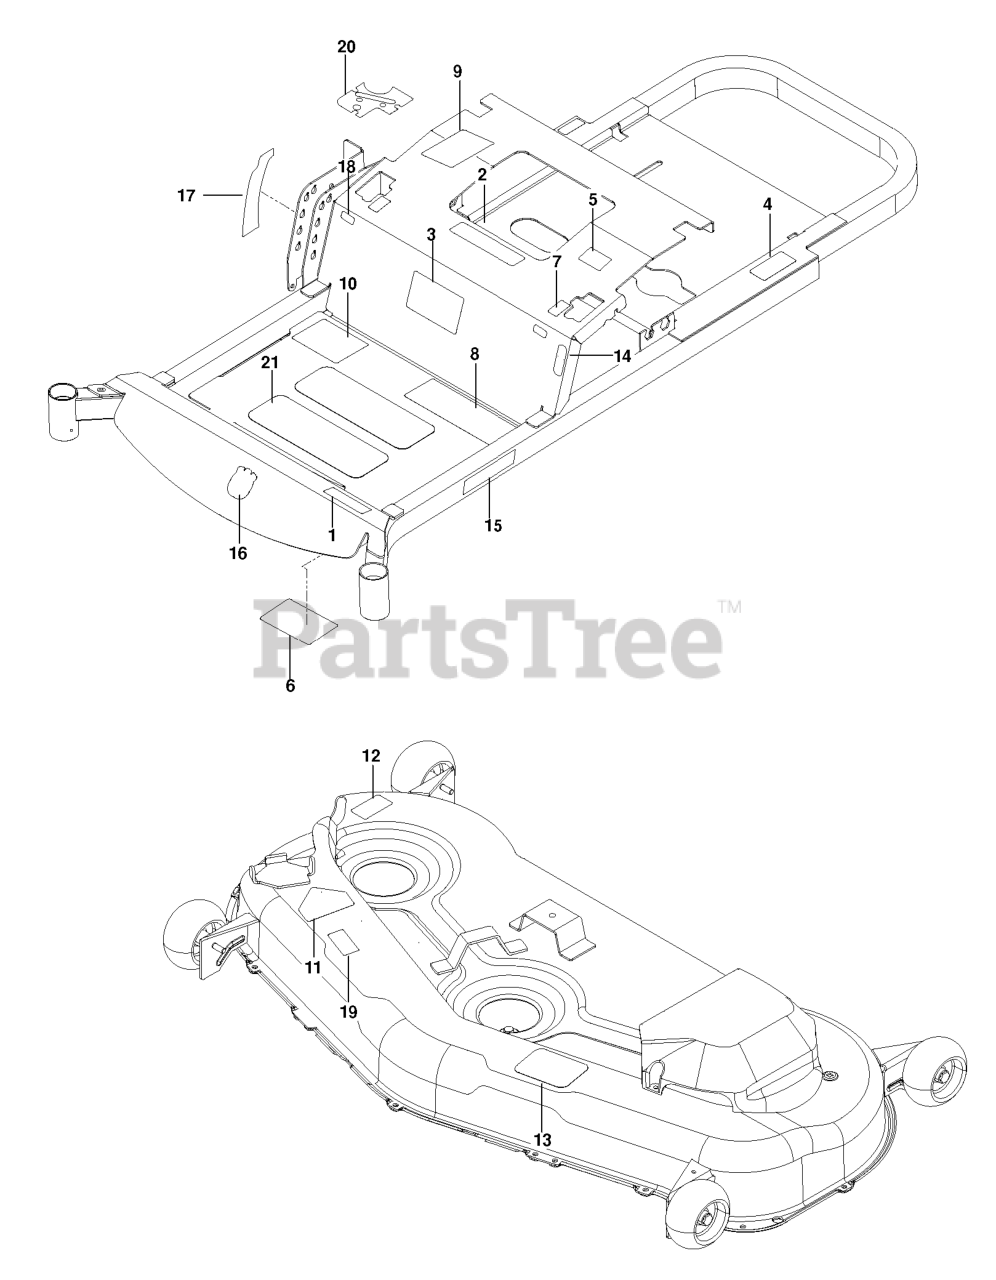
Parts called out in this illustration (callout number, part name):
1	DECAL, RZ5424
2	EURO DECAL-BATTERY WARNIN6
3	DECAL, START
4	DECAL, DO NOT TOW
5	DECAL, EXITING MOWER
6	DECAL, SERVICE
7	DECAL, MOTION CONTROL
8	DECAL, SAFETY WARNING
9	DECAL, CUSTOMER RESPNSIBILITY
10	DECAL, WARNING
11	DECAL, CPSC
12	DECAL.DECK.6MIL./DEF.SHLD.WARN
13	DECAL, BELT ROUTING
14	DECAL, PARK BRAKE
15	RP.DECAL.BADGE.170MM.TEXTLOGO
16	DECAL.AUGER.HUSQ.CROWN.SNOW
17	DECAL, DECK HEIGHT, HUSQ
18	DECAL, F.S.T.
19	DECAL, EURO SEVERING
20	DECAL.CNTRLPANEL.C/START.RZ
21	ANTI-SKID PAD
